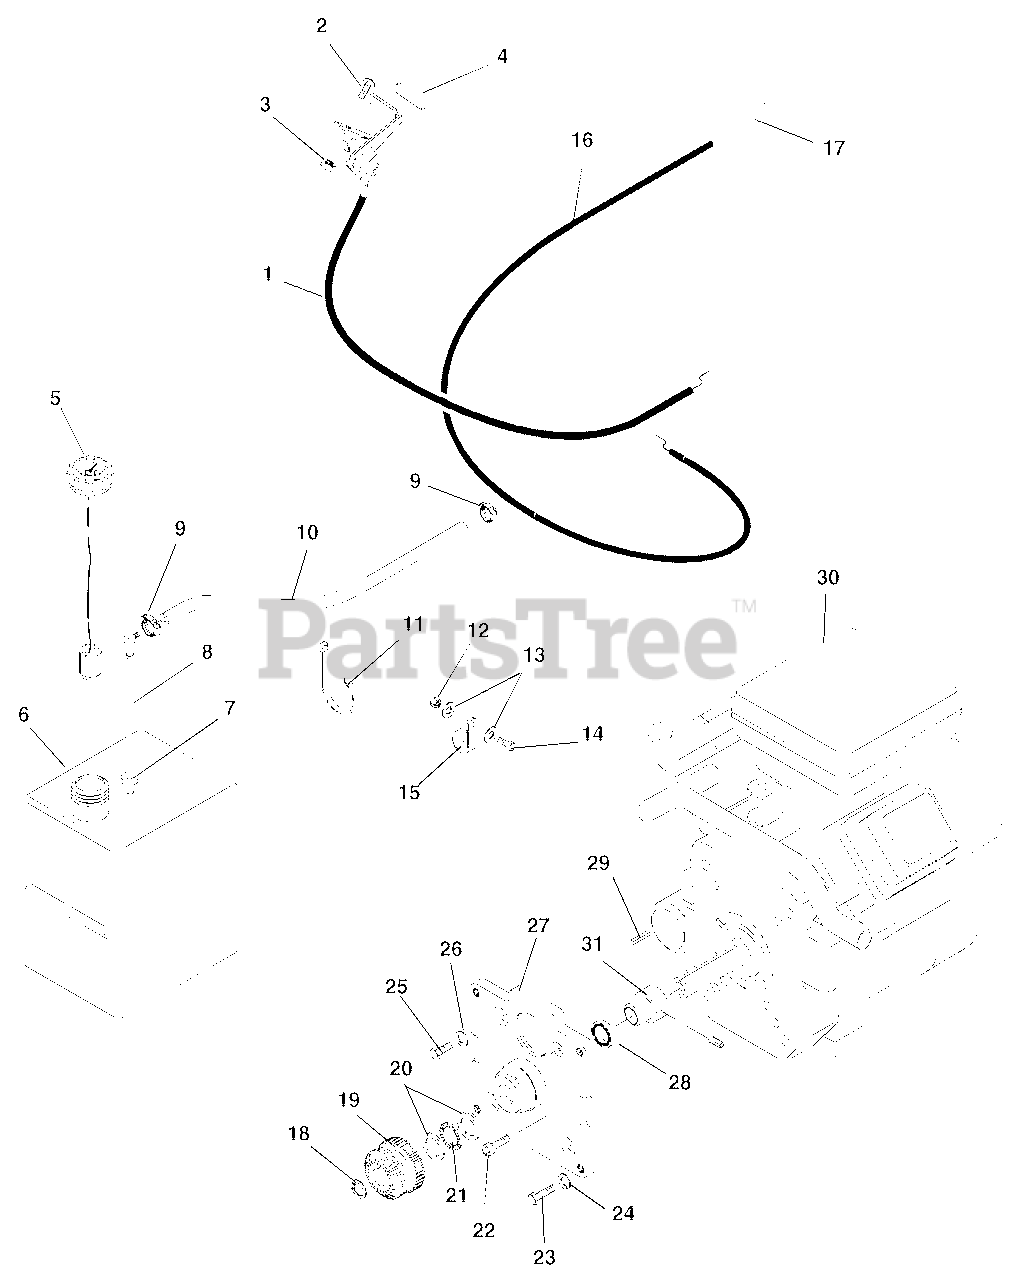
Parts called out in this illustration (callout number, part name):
1	Cable, Throttle
2	Screw-Machine 10-24 x .50 Hex Washer Head
3	Nut-Locking-Nylon 10-24 with Insert
5	Gauge, Fuel
6	Tank, Fuel
7	Bushing
8	Fitting, Tank
9	Hose Clamp
10	Gas Line-Bulk 1/4" I.D.
11	Cable Tie
12	Nut-Locking-Center .31-18
13	Washer-Flat-Steel .34 x .689 x .065
14	Bolt-Hex .31-18 x 1.00 Grade 5
15	Cable Clamp
16	Control, Choke
17	Nut-Jam .38-24
18	Ring-Retaining-Internal 1.11 x .042
19	Gear, Spur and Bevel (Input)
20	Washer-Thrust
21	Bearing-Needle-Thrust 1.00 x 1.55 x .078
22	Screw-Socket Head .44-14 x 1.00
23	Bolt-Hex .50-13 x 1.25 Grade 5
24	Washer-Locking .50 x .125 Regular
25	Bolt-Hex .44-14 x 1.13
26	Washer-Locking .438 X .133 Heavy
27	Adapter, Engine
28	Seal 1.13 x 1.63 x .25
29	Key-Square .25 x 1.25 x .25
30	Engine, 16HP Briggs & Stratton Vanguard
31	Spacer-Special Engine
